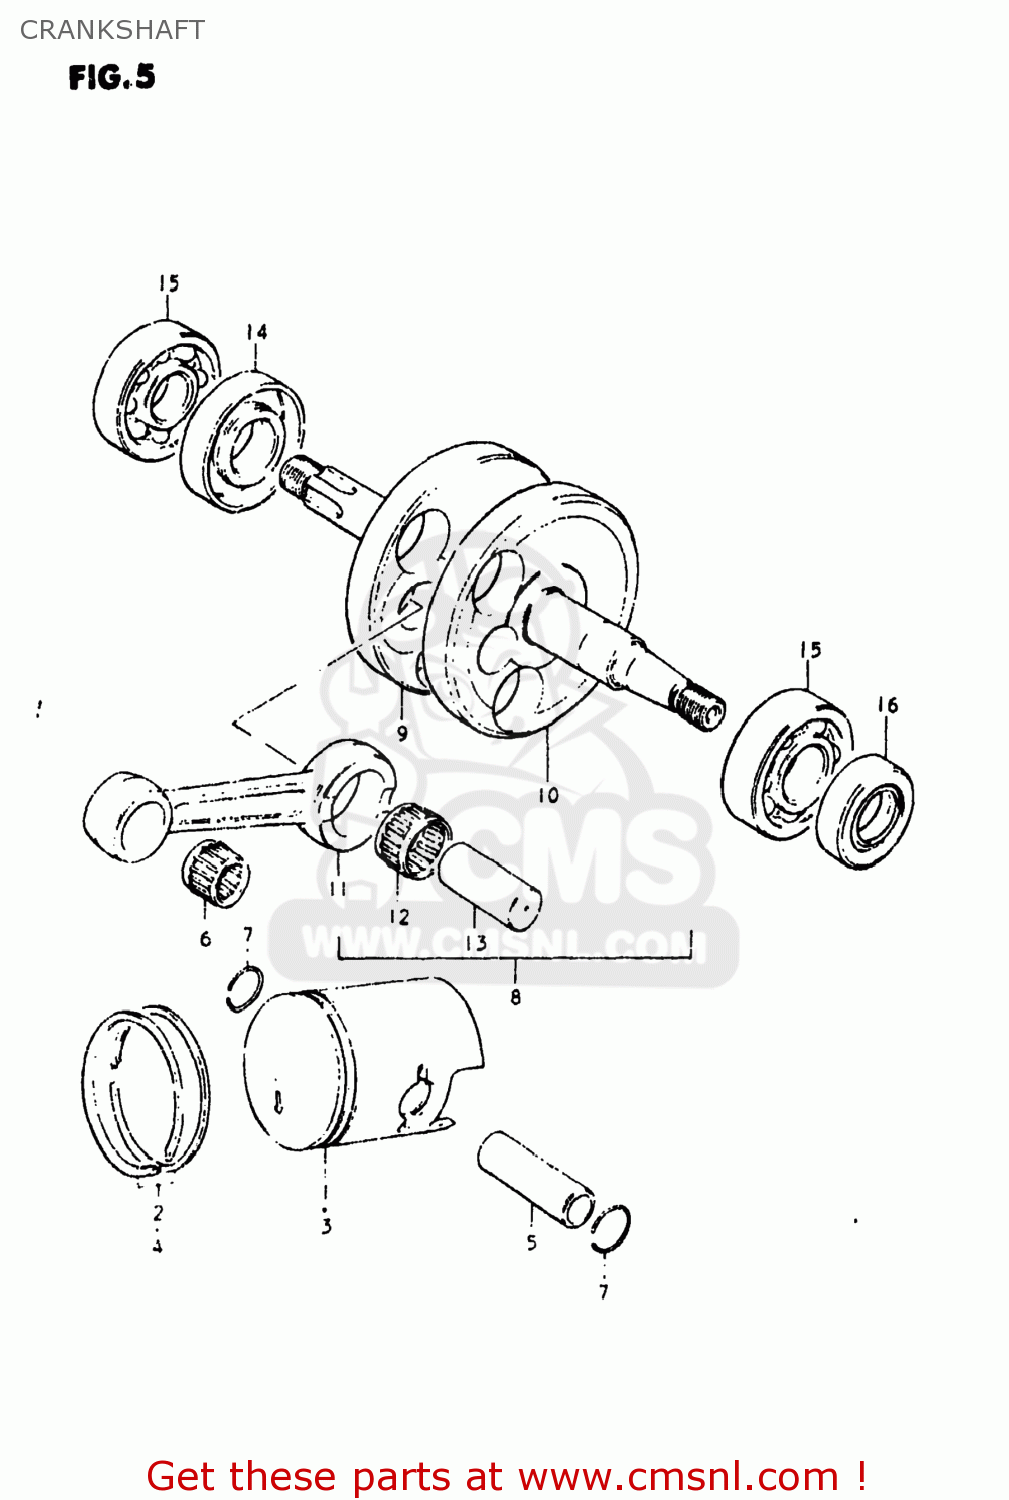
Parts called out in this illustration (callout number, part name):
1	PISTON
2	RING SET,PISTON
3	PIN,PISTON
4	BEARING
5	RING,SNAP
6	CRANKSHAFT ASSY
7	CRANKSHAFT,L
8	ROD,CONNECTING
9	BEARING
10	BEARING(15X21X9.8)
11	PIN,CRANK
12	SEAL,OIL(22X40X8)
13	BEARING
14	OIL SEAL (17X29X7)
